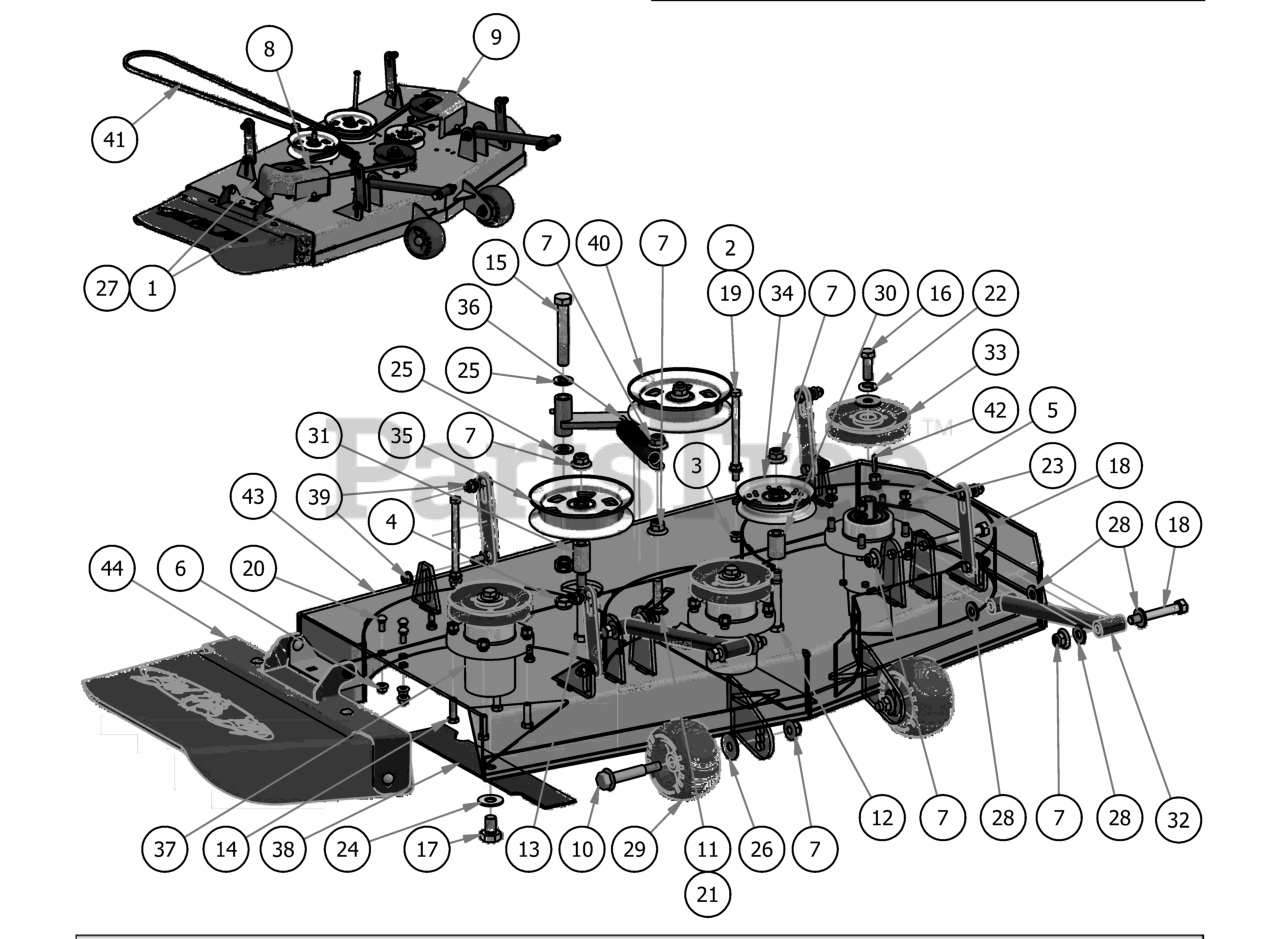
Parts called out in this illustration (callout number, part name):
1	Acorn nut-pulley Cover
2	3/8" Flange Nut
3	3/8" Nylock Flange Nut
4	5/8-11 Nylon Insert Jam Half Nut
5	3/8" Hex Nut
6	5/16" Nylon Flange Nut
7	1/2-13 Nylon Flange Nut
8	pulley cover chute side
9	pulley cover non-chute side
10	Deck Wheel Bolt
11	1/2 x 2" Carriage Bolt
12	1/2 x 3 1/2 Flange Bolt Grade 8
13	1/2" x 4" Bolt (Grade 8)
14	3/8" x 1 1/4" Hex Bolt
15	5/8" x 4" Hex Bolt
16	1/2"-20 x 1 1/2 - Grade 5 Fine Thread Bolt
17	5/8" x 1 1/2" Grade 8 Hex Bolt (Fine)
18	1/2-13 x 3 1/2 GR 5 Hex Bolt
19	3/8-16 x 5 1/2 Hex Bolt
20	5/16-18x3/4 carriage bolt
21	.517 Square Hole Round Washer
22	1/2" Lock Washer Zinc
23	3/8" Lock Washer
24	5/8'' Flat Washer
25	.630 ID Plastic Washer
26	1/2" Belleville Washer
27	.360 ID Plastic Washer-Black
28	.505 Nylon Spacer
29	Deck Wheel
30	.502 ID X .750 OD X 1.500 Long Spacer
31	1 3/4" Pulley Spacer
32	MZ/ZT Deck Locator
33	MZ Deck Pulley
34	4 3/4 Idler Pulley - ABFI-76
35	5-3/4 Idler Pulley
36	Deck Idler Spring
37	Spindle Assembly-MZ
38	MZ 42 Blade
39	Deck Hanger Assembly
40	2017 54"/48" Deck Idler Assembly
42	3/16 x 1 Square Key
43	2017 42" MZ Deck-Welded Shell
44	MZ Discharge Chute Assembly
